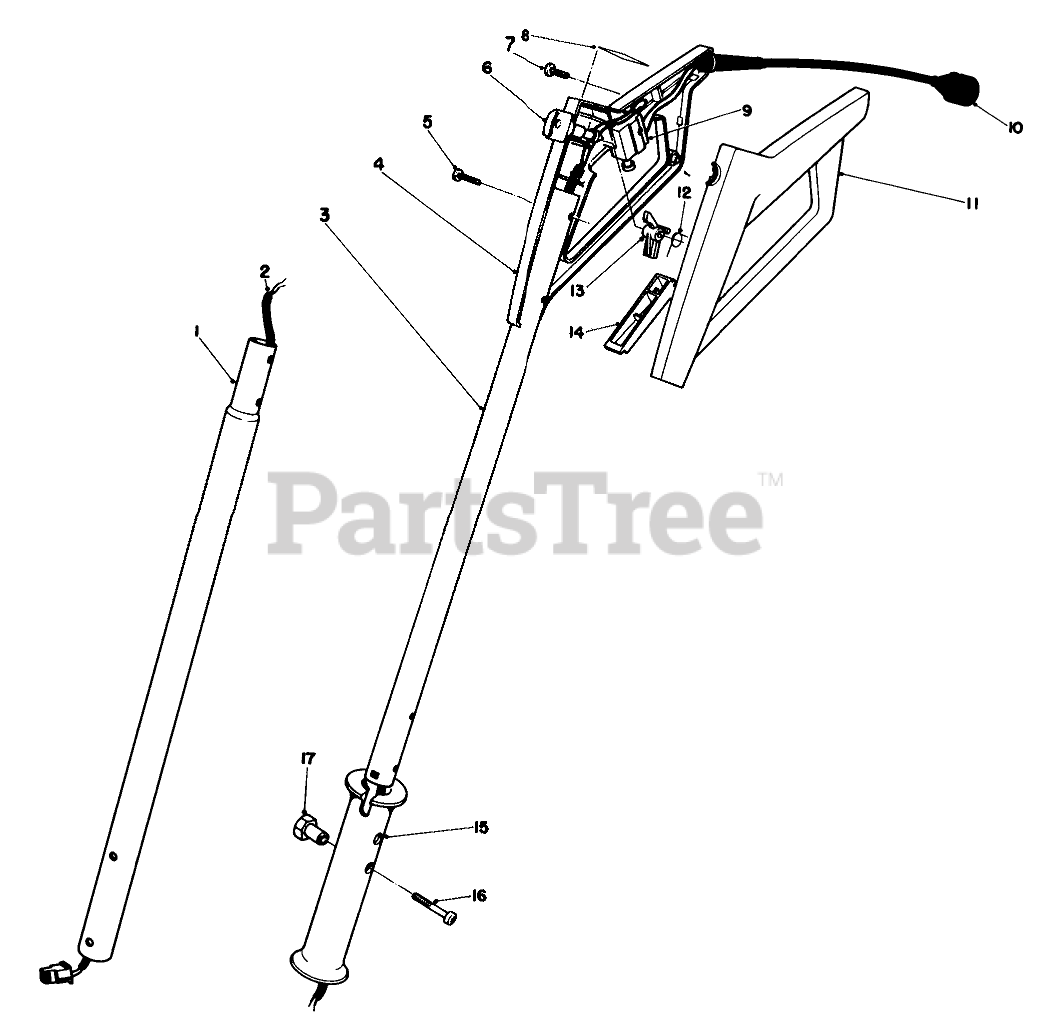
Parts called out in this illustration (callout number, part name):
1	LOWER TUBE, P. SHOVEL
2	Wire Harness
3	Tube-Upper Handle
4	Grip-Control R.H.
5	Screw
7	SCREW-PPH
8	UL GRIP DECAL
9	SWITCH-STARTER
10	Cord-Supply
11	Grip-Control L.H.
12	TORSION SPRING
13	LOCKOUT
14	SWITCH BAR,POWER SHOVEL
15	Grip-Handle
16	SPEC PAN HD SCREW
17	SPECIAL HEX NUT
